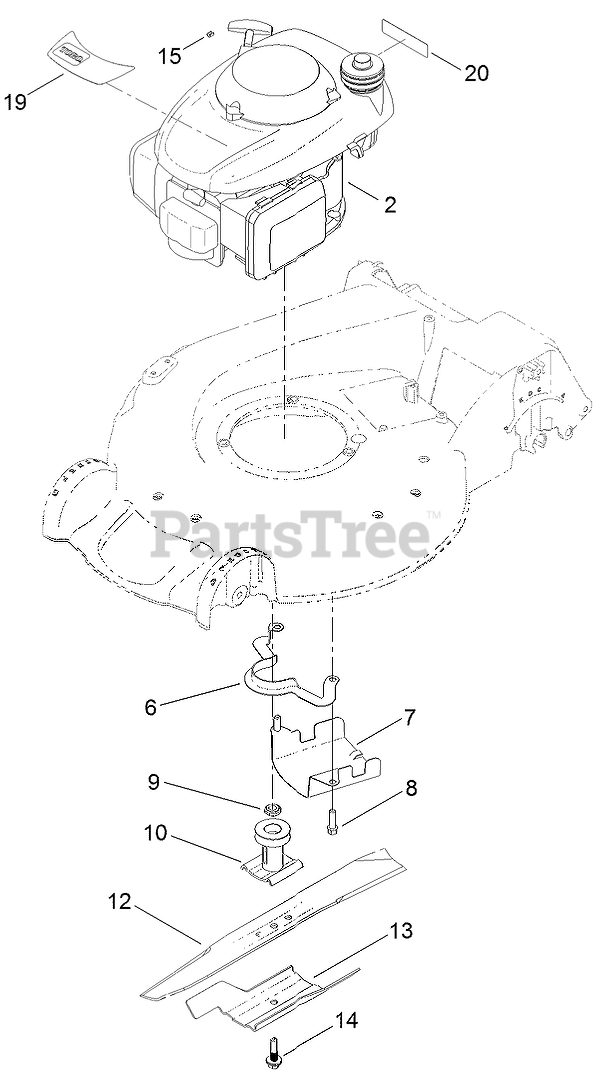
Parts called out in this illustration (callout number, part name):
6	GUIDE-BELT
7	SHIELD-GRASS
8	SCREW-TAPTITE
9	Spacer-Driver
10	DRIVER-BLADE
12	BLADE-RECYCLING
13	Accelerator-Blade
14	BOLT-BLADE
15	STOP-ROPE
19	DECAL-ENGINE
20	DECAL-ARRESTER, SPARK
